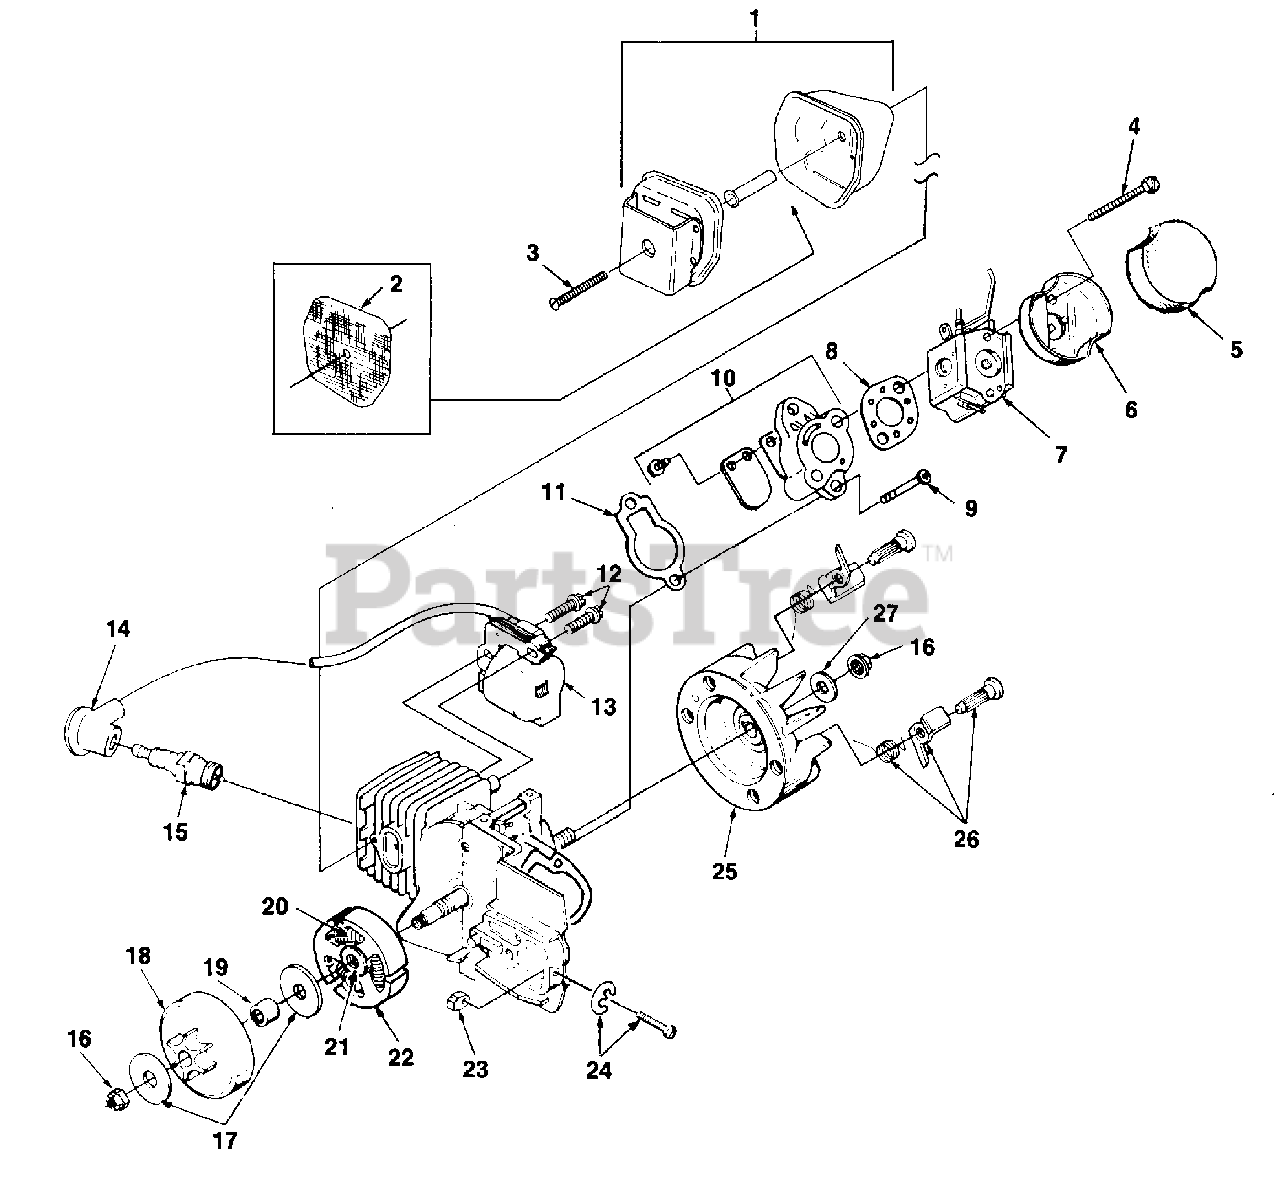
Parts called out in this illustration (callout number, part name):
1	MUFFLER- Complete
2	SCREEN- Spark Arrestor
3	SCREW- Sems (10-24 x 17/8")
4	SCREW- Thd. Form (8-16 x 1 3/4") (UT-10705)
5	FILTER- Air
6	CUP- Filter (UT-10705)
7	CARBURETOR- Walbro (UT-10705)
8	GASKET- Carburetor
9	SCREW- (10-24 x 7/8")
10	HEAT DAM & REED
11	GASKET- Heat dam
12	SCREW- Taptite (8-32 x 1")
13	MODULE- Ignition
14	TERMINAL
15	SPARK PLUG
16	NUT- (5/16-24)
17	WASHER- Thrust
18	SPROCKET & DRUM
19	BEARING
20	SPRING- Clutch
21	SPIDER- Clutch
22	SHOE- Clutch
23	PIN- Adjusting
24	SCREW & E RING KIT
25	ROTOR & STARTER PAWLS
26	STARTER PAWL KIT
27	WASHER (5/16")
